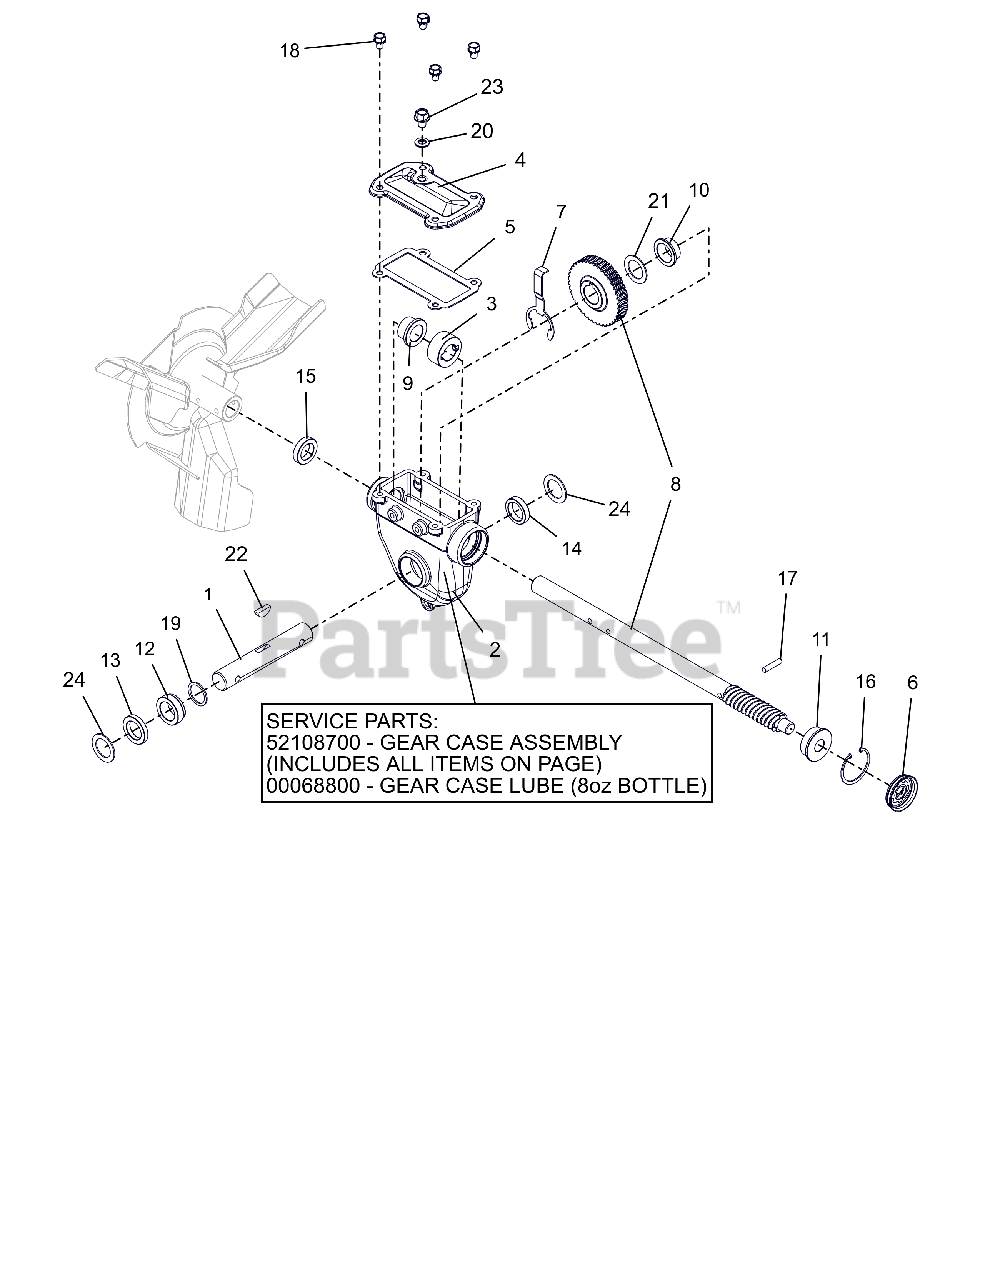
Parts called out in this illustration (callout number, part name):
1	RAKE SHAFT, SHORT-COMMON
2	GEARCASE, LARGE MACHINED
2	KIT, SERVICE - DLX GEAR CASE
2	ARIENS L3 LUBE, 8 OZ BOTTLE
3	THRUST COLLAR, .875"ID SLIPFIT
4	COVER, TOP - LARGE IRON
5	GASKET, TOP - LARGE GEARCASE
6	COVER, GEAR CASE 1.75"
7	BUSHING RETAINER, LARGE
8	KIT, SERVICE-WORM SHAFT & GEAR
9	BSHG-FLG .879X1.128X.75X1.45
10	BSHG-FLG 1.006X1.128X.555X1.45
11	BSHG-FLG .628X1.503X.58X1.725
12	BSHG-FLG LARGE, RIGHT
13	SEAL-OIL .999X1.500X.250 TBC29
14	SEAL-OIL .999X1.375X.312 TBC29
15	SEAL-OIL .873X1.375X.312 TBC29
16	RG-RTNG-INT 1.750X.062
17	PIN-STR .250X1.12 6150
18	BLT, SEMS .31-18X.50 G5 ZCC
19	WSHR-FL-STL 1.010X1.250X.068YZ
20	WSHR-BND-SEAL .38X.75X.11 GALV
21	WSHR-FL-STL 1.010X1.505X.062YZ
22	KEY-WDRF .25X.875 HRD #A
23	@SCR-ROLOK .38-16X.50 HWH YWZC
24	WSHR, FLT 1.010X1.505X.062 ZCC
